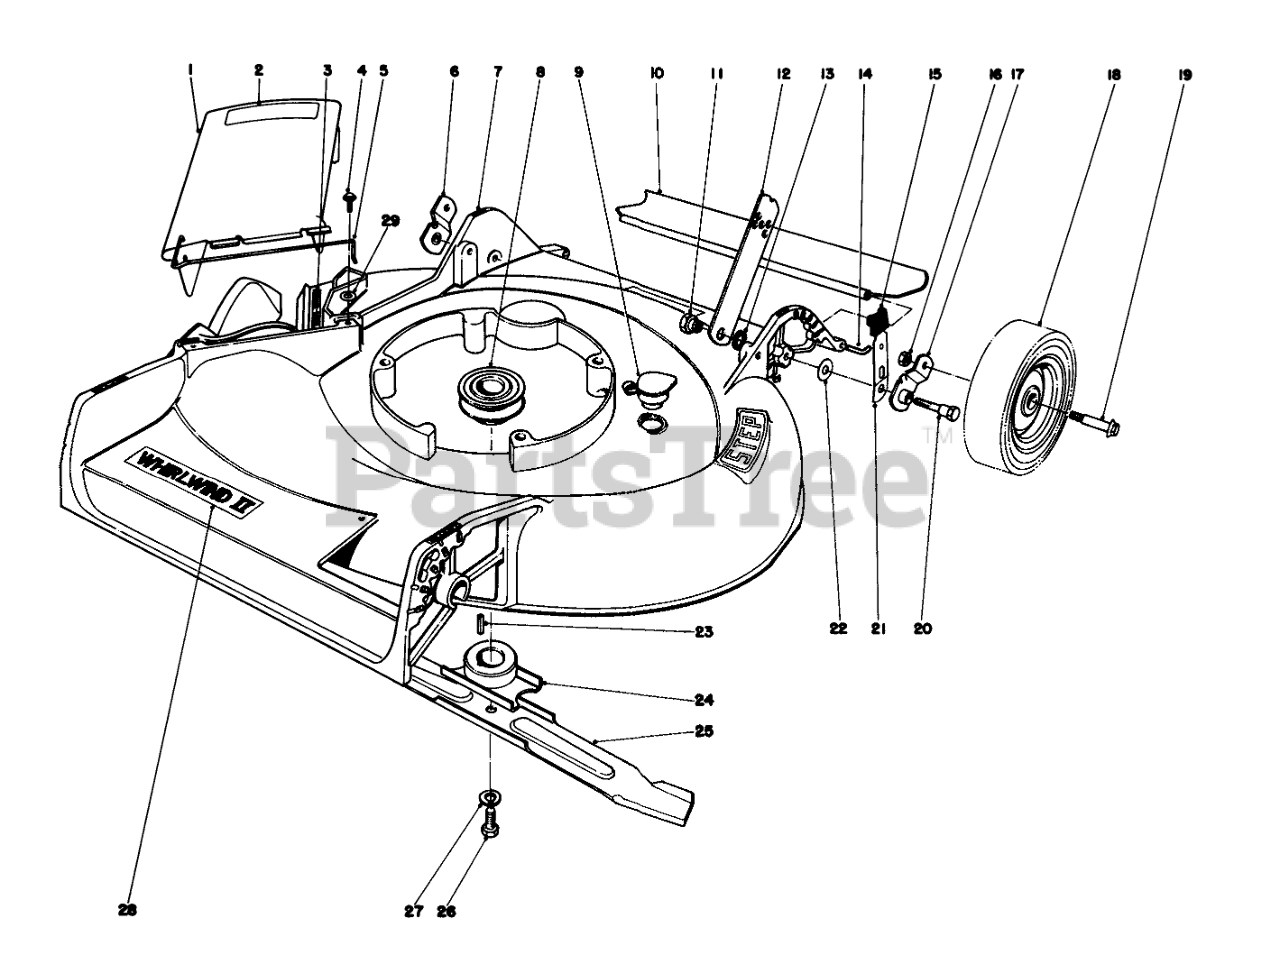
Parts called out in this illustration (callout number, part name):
1	Deflector Assembly (Incl. Ref. 2 & 5)
2	Caution Decal
3	Decal
4	SCREW
5	SPRING HINGE
6	Pivot Arm
7	Housing
8	DRIVER PULLEY
9	WASHOUT PLUG
10	Rear Shield
11	HANDLE PIVOT NUT
12	HANDLE LATCH
13	HANDLE LATCH SPACER
14	SHIELD ROD
15	KNOB-ARM
16	Nut
17	Pivot Arm
18	Wheel Assembly
20	PIVOT SCREW
21	SPRING ARM ASM
22	WASHER-PIVOT
23	KEY-SQUARE
24	Blade Retailer
25	Blade
26	SPECIAL SCREW
27	WASHER-LOCK
28	Decal Whirlwind
29	WASHER-FLAT
